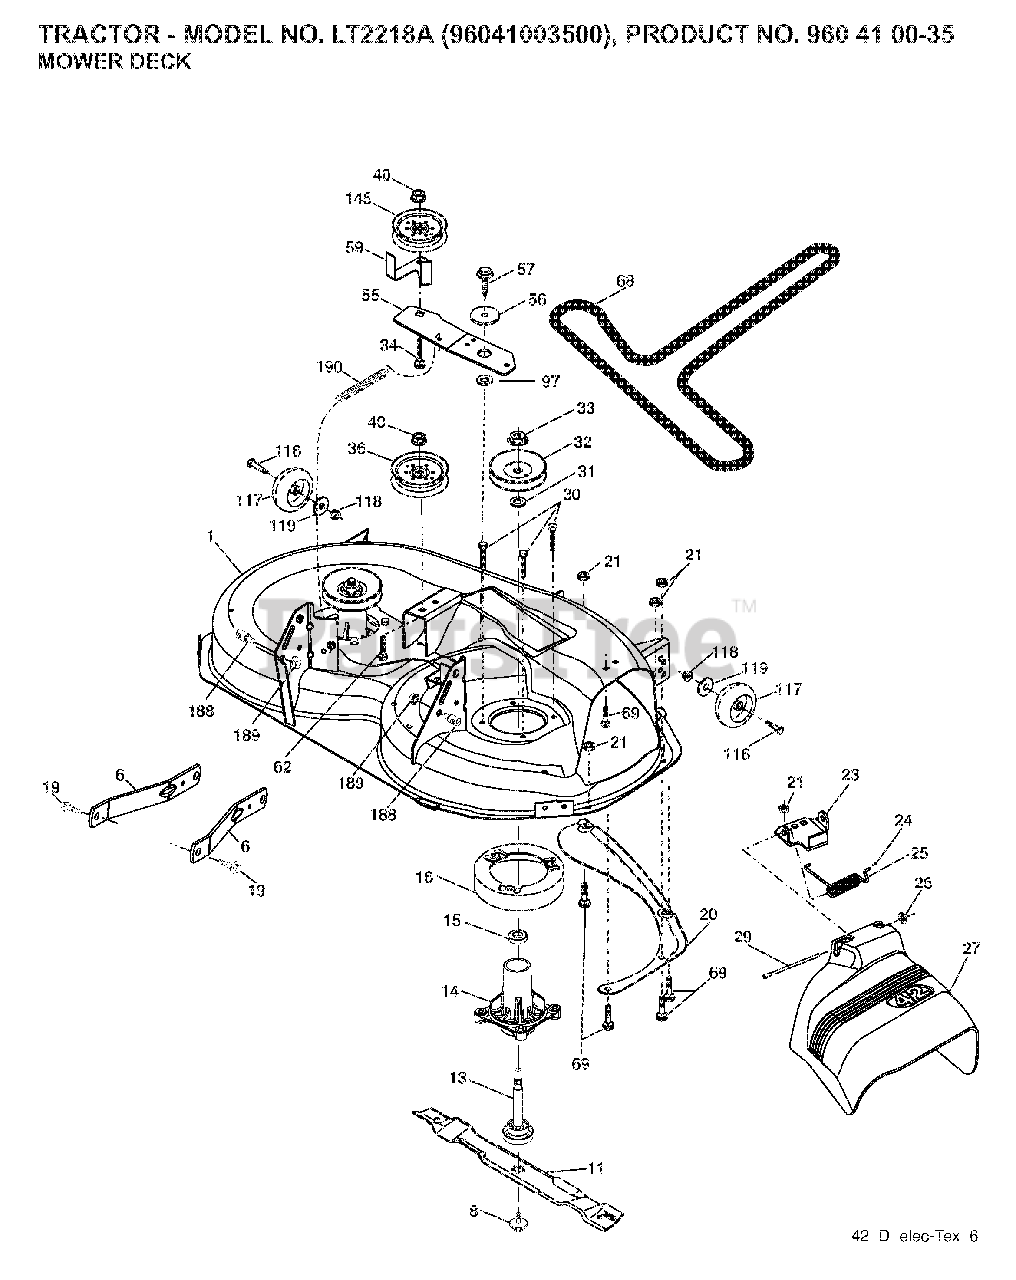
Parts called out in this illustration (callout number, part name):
1	DECK.WELDMENT.42"
6	ARM.SUSPENSION.MOWER.R
8	BOLT.WASHER.ASM.7/16-2
11	42" HI-LIFT BLADE
13	SHAFT.ASM.MDRL.N/GREASE.38
14	HOUSING MANDREL
16	STRIPPER, MWR ROUND
19	BOLT.SHOULDER
20	BAFFLE.VORTEX
21	LOCKNUT
23	BRKT.DEFLECTOR.38"2005+
24	CAP-SLEEVE LT
25	SPRING.TORSION.DEFLECT
26	NUT PUSH M
27	SHIELD.DEFLECTOR.MOWER.42"BLAC
29	ROD.HINGE
30	SCREW, WASHER HEAD
31	WASHER.SPACER.MANDREL
32	PULLEY/MANDREL
33	NUT.FLANGE.LOCK.TOP
34	BOLT.3/8-16X1.50
36	PULLEY.IDLER.2006
40	NUT LOCK FLG 3/8-16 UNC
55	IDLER.ARM
56	SPACER.RETAINER
57	SCREW 3/8-16X1
59	GUARD, BELT
62	BOLT
68	BELT V SECONDARY
69	BOLT
117	WHEEL.GAGE.HALF.SPOKED
118	LOCKNUT
119	WASHER
145	PULLEY.IDLER.48"PRIMARY
188	STUD.FASTNER.W/ANTI-ROTATE
189	NUT LOCK HEX FLANGE 5/16-18
190	SPRING.MOWER.DRIVE.ELECTRIC
